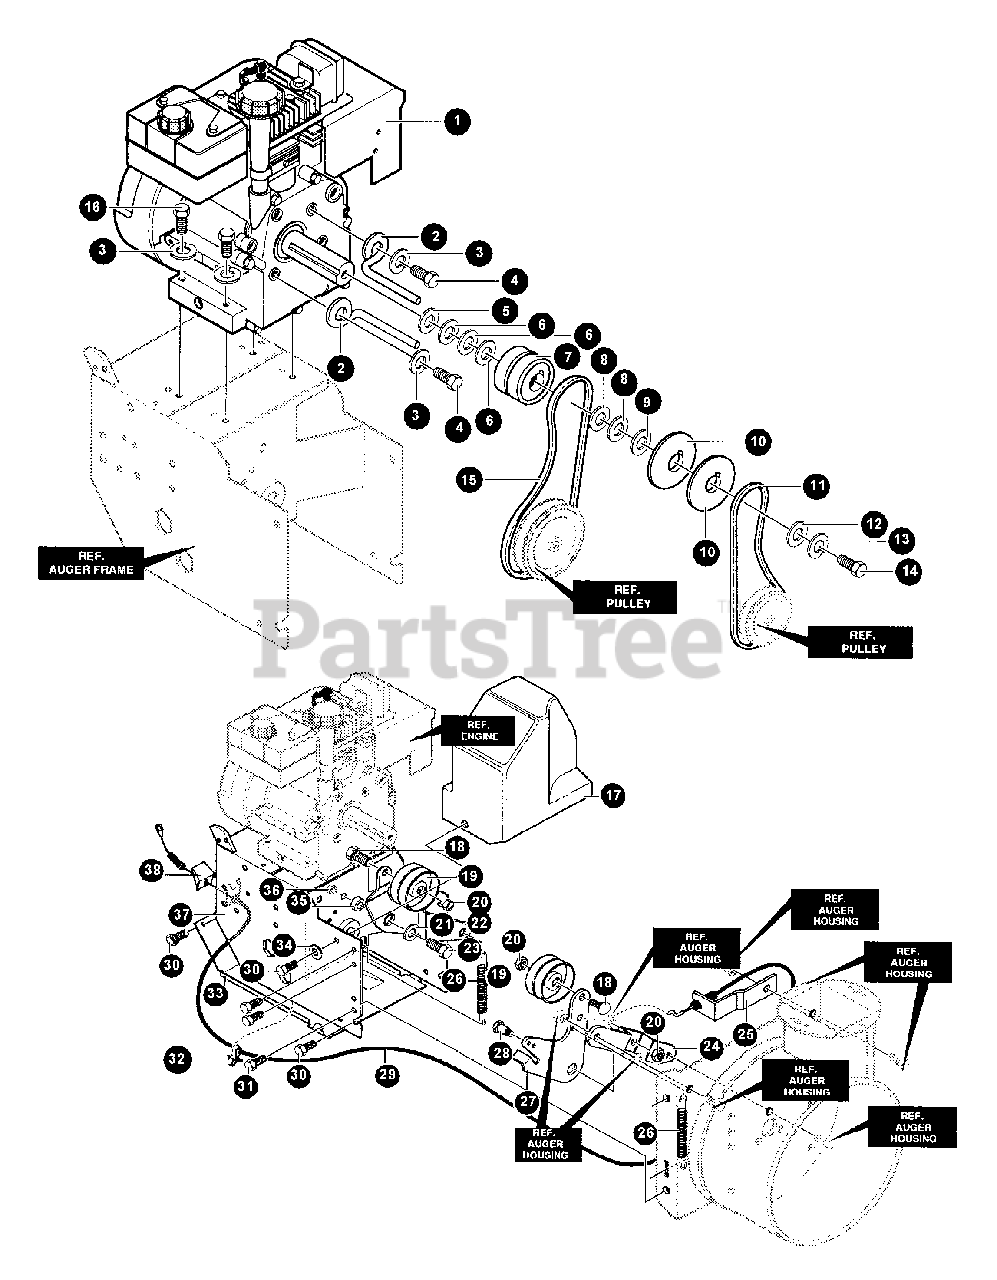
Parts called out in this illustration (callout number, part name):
1	ENGINE, 5 HP TEC
2	GUIDE, ROD BELT - RIGHT
3	LOCKWASHER
4	SCREW - 5/16-24 X 5/8"
5	WASHER
6	WASHER, FLAT .752X.91X.02
7	PULLEY, HALF
8	WASHER
9	SPACER
10	PULLEY, ENGINE
11	BELT, V 4L 35.23 LG
12	WASHER
13	LOCKWASHER
14	SCREW - 3/8-24 X 1.00" -- NYLON
15	BELT, V 3L 33.13LG
16	SCREW - 5/16-18
17	COVER, BELT
18	SCREW - 3/8-16 X 1-1/4"
19	PULLEY, IDLER
20	LOCKNUT - 3/8-16
21	WASHER - .328X1.25X.075
22	LEVER, IDLER ARM TRACTION
23	SCREW - 5/16-18 X 3/4"
24	PLATE, CLUTCH
25	BRACKET, COMPACT CABLE MTG.
26	SPRING, IDLER
27	SHOE, CLUTCH
28	BOLT - 3/8-16
29	CABLE, AUGER
30	SCREW - 1/4-20 X .63" -- TAPPING
31	SCREW - 5/16-18 X 1/2"
32	CLIP, CABLE
33	COVER, BOTTOM
34	WASHER
35	BUSHING, IDLER LEVER
36	NUT - 5/16-18
37	FRAME ASSY
38	SHIELD, CABLE GUARD
